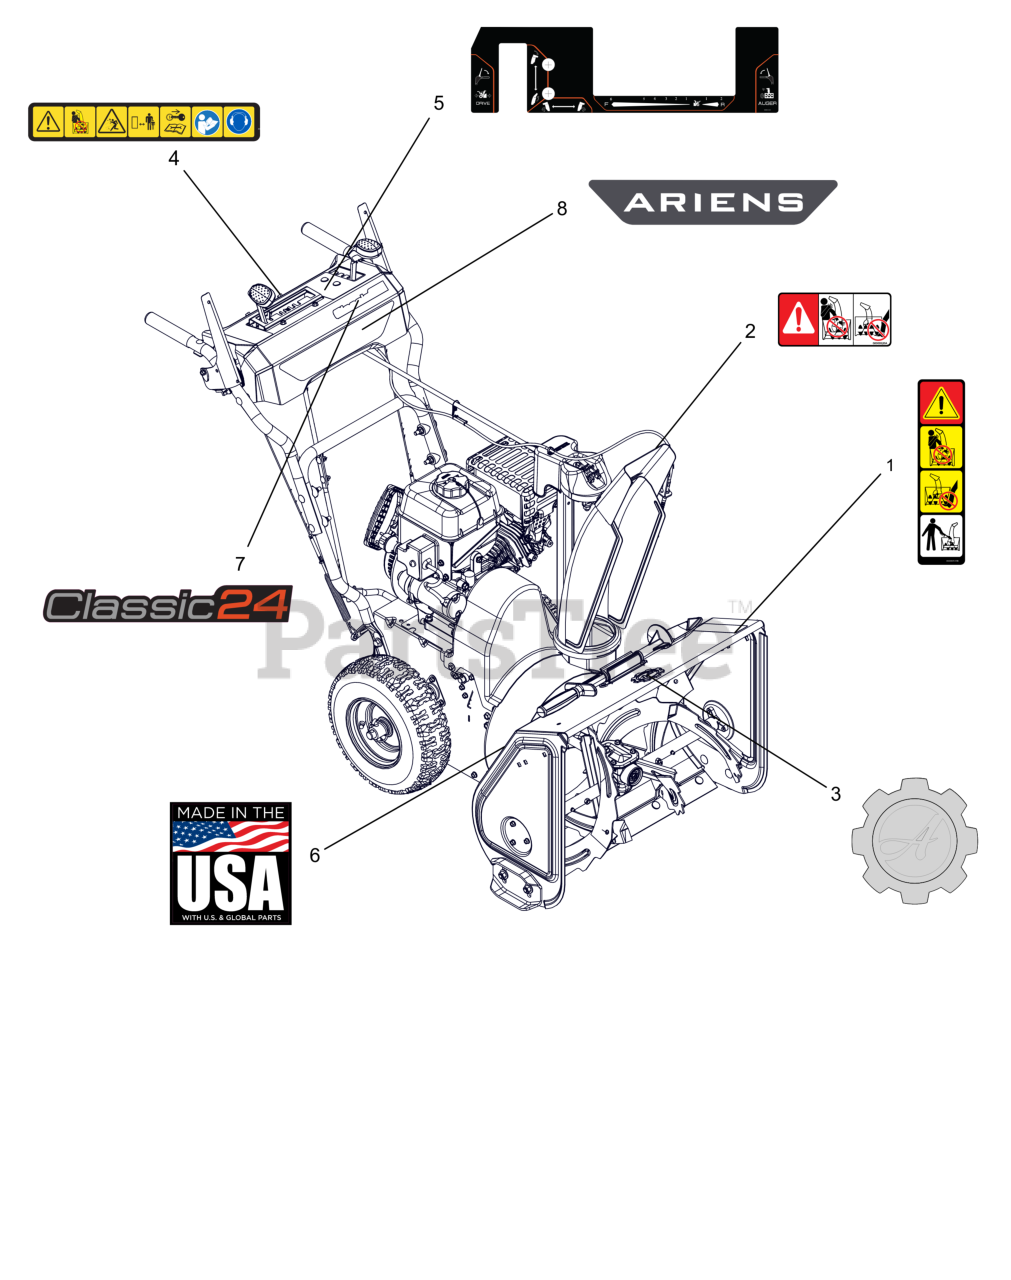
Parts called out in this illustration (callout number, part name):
1	DECAL, DANGER - ROTATING PARTS
2	DECAL, DANGER
3	DECAL, ARIENS-GEAR BADGE -THK
4	DECAL,DASH - SAFETY
5	DECAL,CONTROL-COMP REMOTE
6	DECAL, MADE IN USA
7	DECAL, DASH - CLASSIC 24
8	DECAL, DASH BRAND - ARIENS PB
